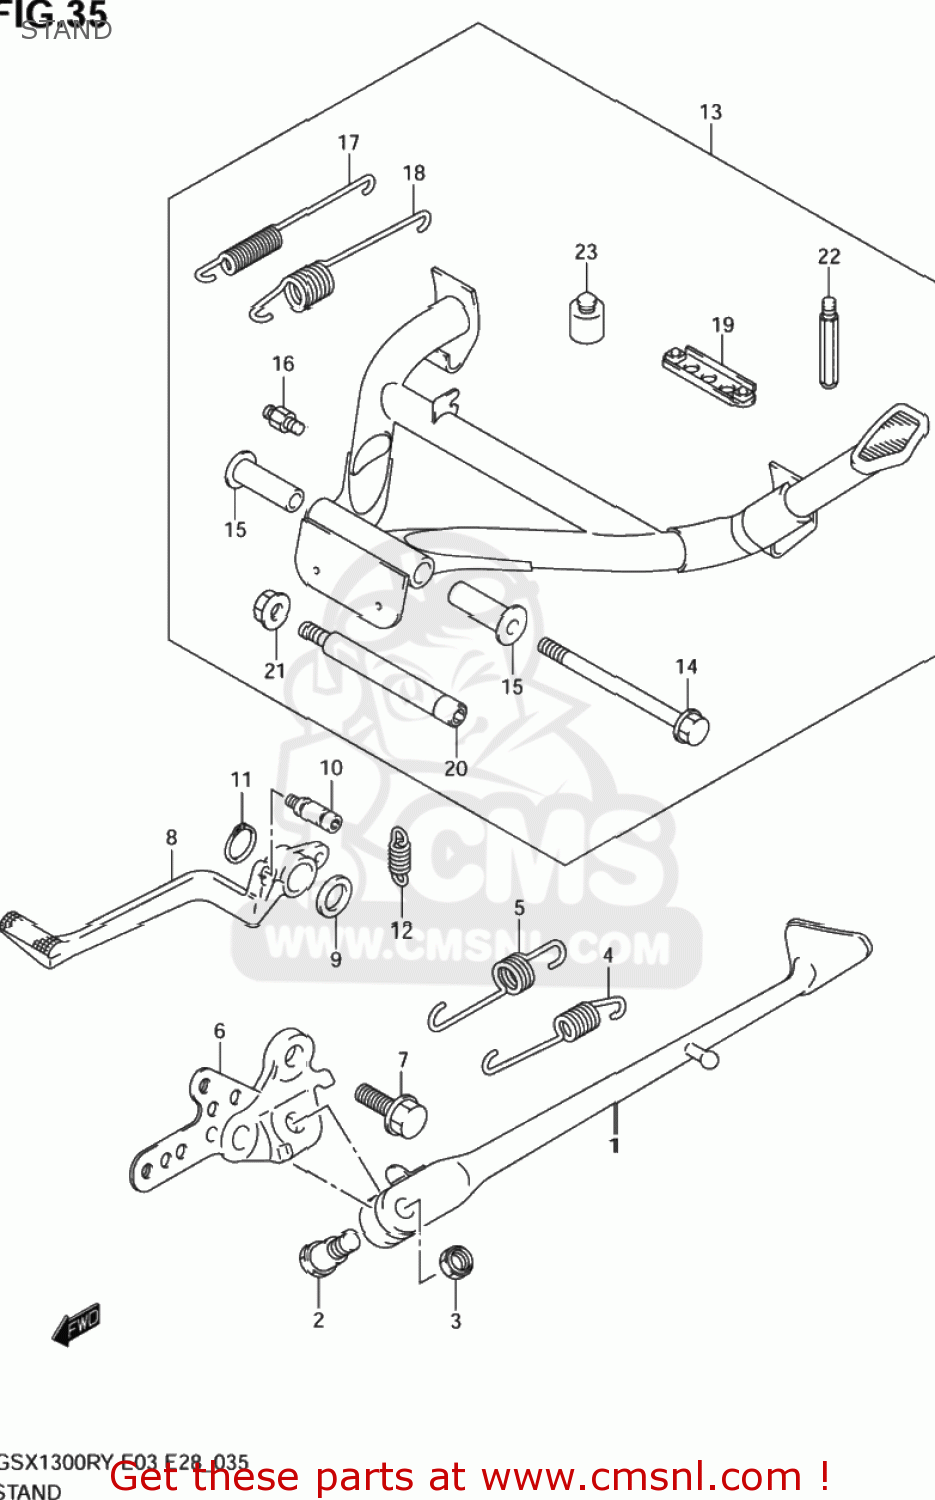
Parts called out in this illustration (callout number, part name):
1	STAND,PROP
2	BOLT(10X21)
3	NUT
4	SPRING
5	SPRING
6	BRACKET COMP,PROP STAND
7	BOLT
8	PEDAL,BRAKE
9	WASHER(18X24X1)
10	HOOK,RETURN SPRING
11	CLIP
12	SPRING
13	STAND SET,CENTER
14	BOLT,CTR STAND
15	SPACER,CTR STAND
16	HOOK,CTR STAND SPRING
17	SPRING
18	SPRING
19	BRACKET,UNDER COWLING OP
20	BOLT,CTR STAND STOPPER
21	NUT
22	BOLT,BANK SENSOR
23	CUSHION
